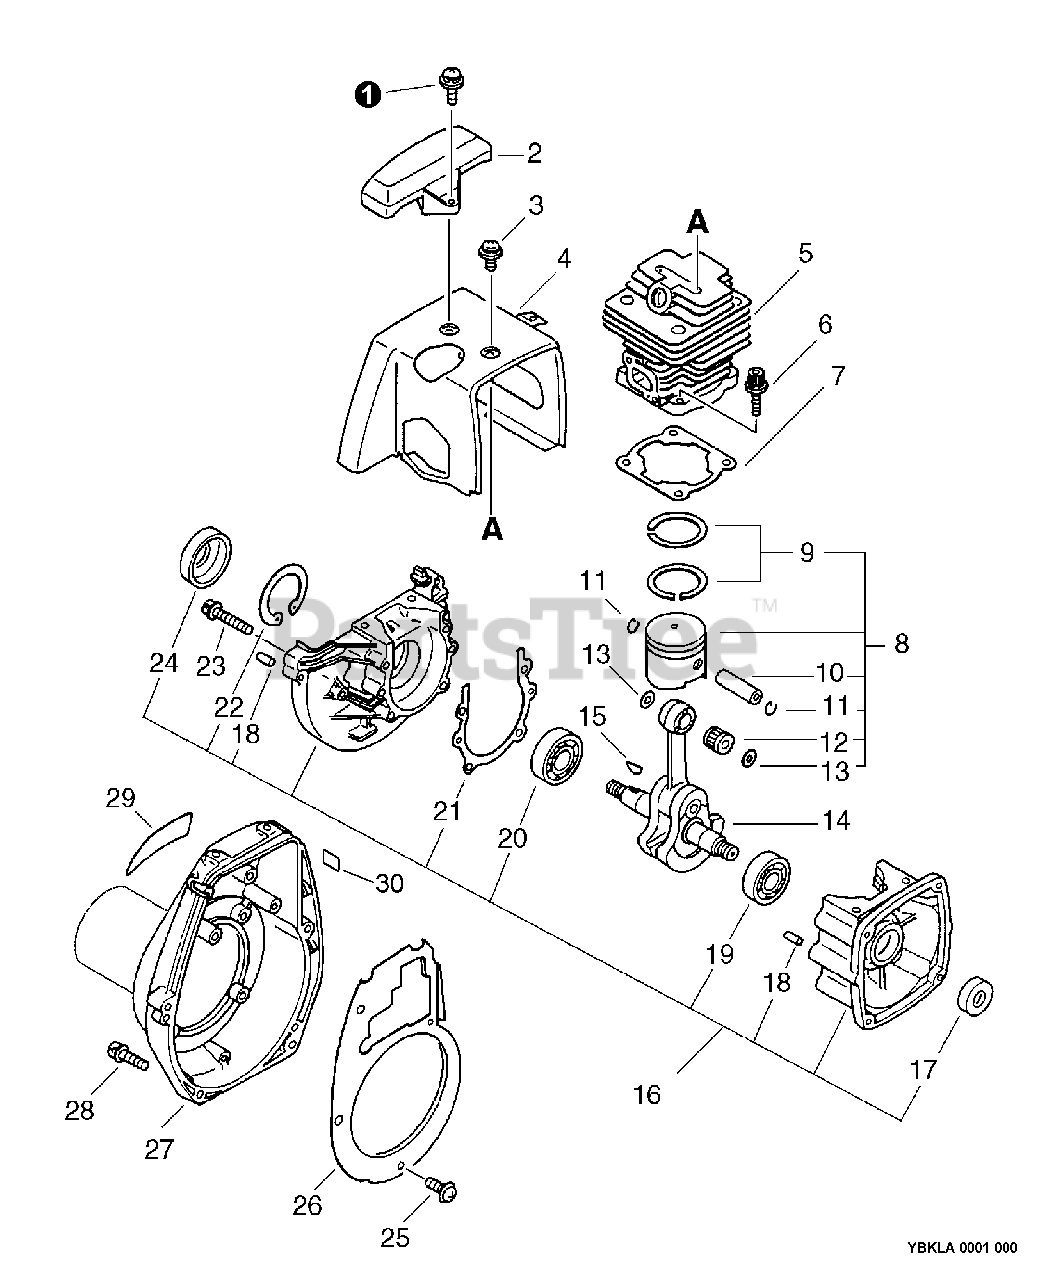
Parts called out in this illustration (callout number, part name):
1	SCREW 5×14
2	GUARD, TOP
3	SCREW 5×10
4	COVER, ENGINE
5	CYLINDER
6	BOLT 5×20
7	GASKET, CYLINDER
8	PISTON KIT
9	RING, PISTON
10	PIN, PISTON
11	RING, SNAP Ø10
12	BEARING, NEEDLE 10
13	WASHER, THRUST 10
14	CRANKSHAFT ASSY
15	KEY, WOODRUFF
16	CRANKCASE KIT
17	SEAL, OIL 12
18	PIN, LOCATING 5×10
19	BEARING, BALL - 6201 C3
20	BEARING, BALL 6202
21	GASKET, CRANKCASE
22	RING, SNAP 35
23	BOLT 5×30
24	SEAL, OIL 18
25	SCREW 4×10
26	SHIELD, FAN
27	COVER, FAN
28	BOLT 5×25
29	LABEL - MODEL SRM-4605
30	LABEL, CAUTION - HOT
